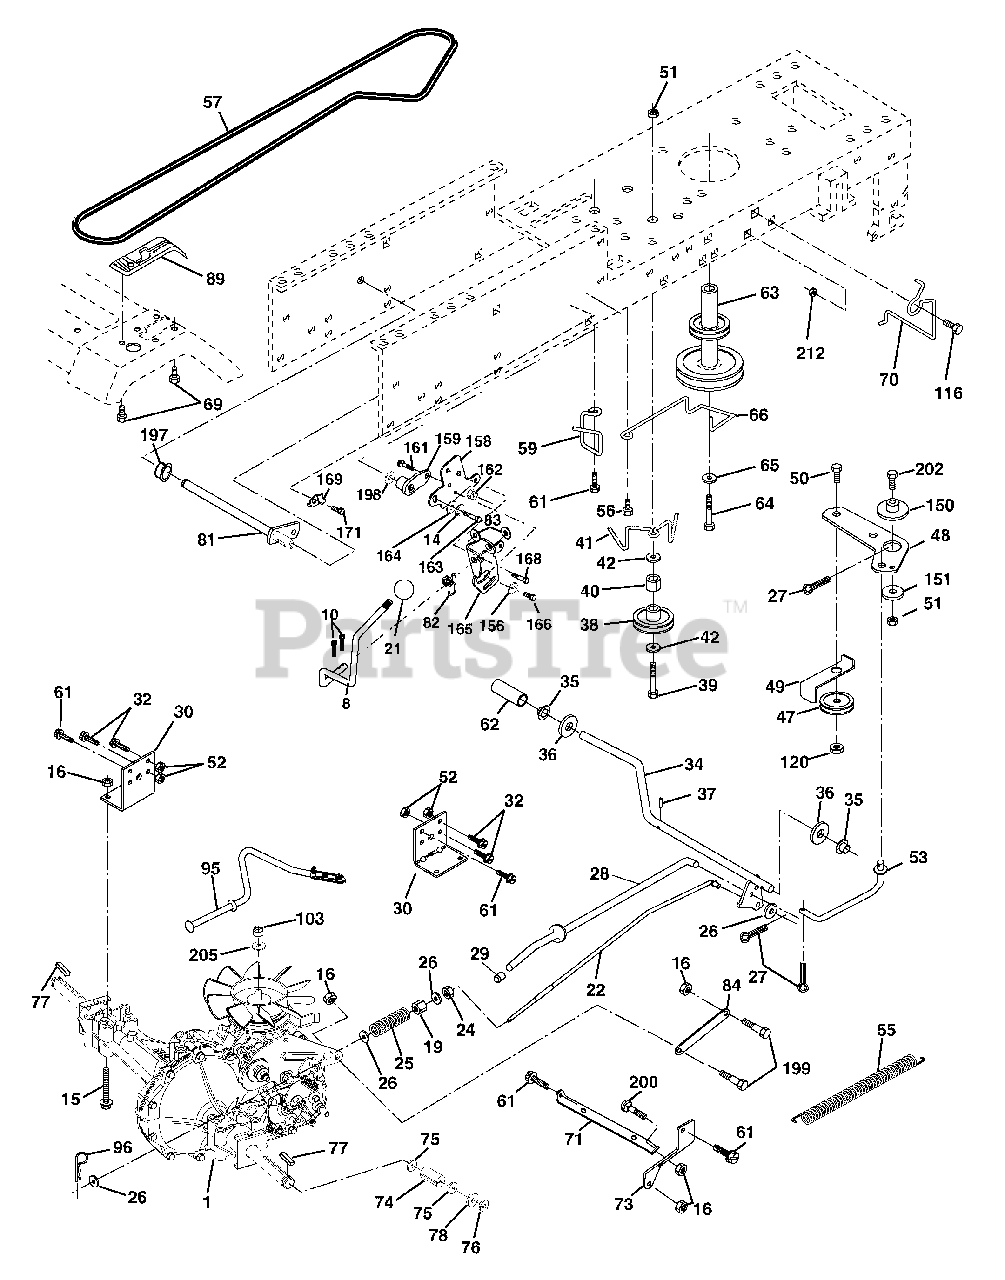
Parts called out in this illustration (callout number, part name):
10	Pin, Cotter 1/8 x 1
14	Washer Lock 1/4
15	Bolt Hex Flghd 5/16-18 Gr. 5
16	Nut, Lock Hex w/Ins 5/16-18 UNC
19	Nut, Lock Hex w/Wsh 3/8-16 UNC
21	Knob Rd. 1/2-13 Plstc. Thds. Blk.
22	Rod, Brake
24	Nut
25	Spring, Rod, Brake
26	Washer 13/32 x 13/16 x 16 Ga.
27	Pin, Cotter 1/8 x 3/4
28	Rod, Parking Brake
29	Cap, Parking Brake
30	Bracket, Transmission
32	Bolt Hex 5/16-18 UNC x 3/4
34	Shaft, Foot Pedal
35	Bearing, Nylon
36	Washer
37	Pin, Roll
38	Pulley, Idler, Flat
39	Bolt
40	Spacer, Split
41	Keeper, Belt, Idler
42	Washer 13/32 x 13/16 x 12 Ga.
47	Pulley, Idler, V-Belt
48	Bellcrank Clutch Grnd Drust l
49	Retainer, Belt
50	Bolt
51	Nut
52	Nut Crownlock 5/16-28
53	Link, Clutch
55	Spring, Return, Clutch
56	Screw 3/8-16 x 1
57	V-Belt, Drive
59	Keeper, Belt, Center
61	Screw, 3/8-16 x 3/4
62	Cover, Pedal
63	Pulley, Engine
64	Bolt Hex 7/16 x 4 Gr. 5
65	Washer
66	Keeper, Belt Engine Hydro
69	Screw Hex Wsh Hi-Lo 1/4-1/2 Unc
70	Guide, Belt, Mower Drive RH
71	Strap, Torque, Lh
73	Strap, Torque, Rh
74	Spacer, Axle
75	Washer 25/32 x 1-1/4 x 16 Ga.
76	Ring, E
77	Key, Square
78	Washer 25/32 x 1-5/8 x 16 Ga.
81	Shaft Asm Cross
82	Spring, Torsion
83	Washer 17/32 x 3/4 x 16 Ga.
84	Link Transaxle
89	Console, Shift
95	Control Asm Bypass Hydro
96	Spring, Retainer 1"
103	Nut, Hex Jam Toplock 1/2-20 UNF
116	Bolt 3/8-16 x 1
120	Bolt Hex 3/8-16 x 1-1/2
150	Spacer Retainer
151	Washer 13/32 x 2 x 10
156	Washer 5/16 x 1.0 x 1.25
158	Bracket Shift Mount
159	Hub Tapered Flange Shift
161	Bolt Rdhd Sqnk 1/4-20 x 3/4 Gr. 5
162	Nut Crownlock 1/4-20 Unc
163	Bolt Hex Fin 1/4-20 x 1
164	Washer 5/8 x .281 x 10 Ga.
165	Bracket Pivot Lever
166	Screw 5/16 x 1.0 x .125
168	Bolt Shoulder 5/16-18 x .561
169	Plate Fastening LT
171	Screw Thdrol 3/8-16 x 1/2
197	Nyliner Snap-in 5/8" ID
198	Washer Nyl 7/8ID x .105" HYD
199	Bolt Shoulder 5/16-18 Unc
200	Bolt Rdhd Sqnk 5/16-18 Unc x 1
202	Bolt Car SH 3/8-16 x 1-1/2 Gr 5
205	Washer 17/32 x 1 x 16 Ga
212	Nut Hex Flange Lock
